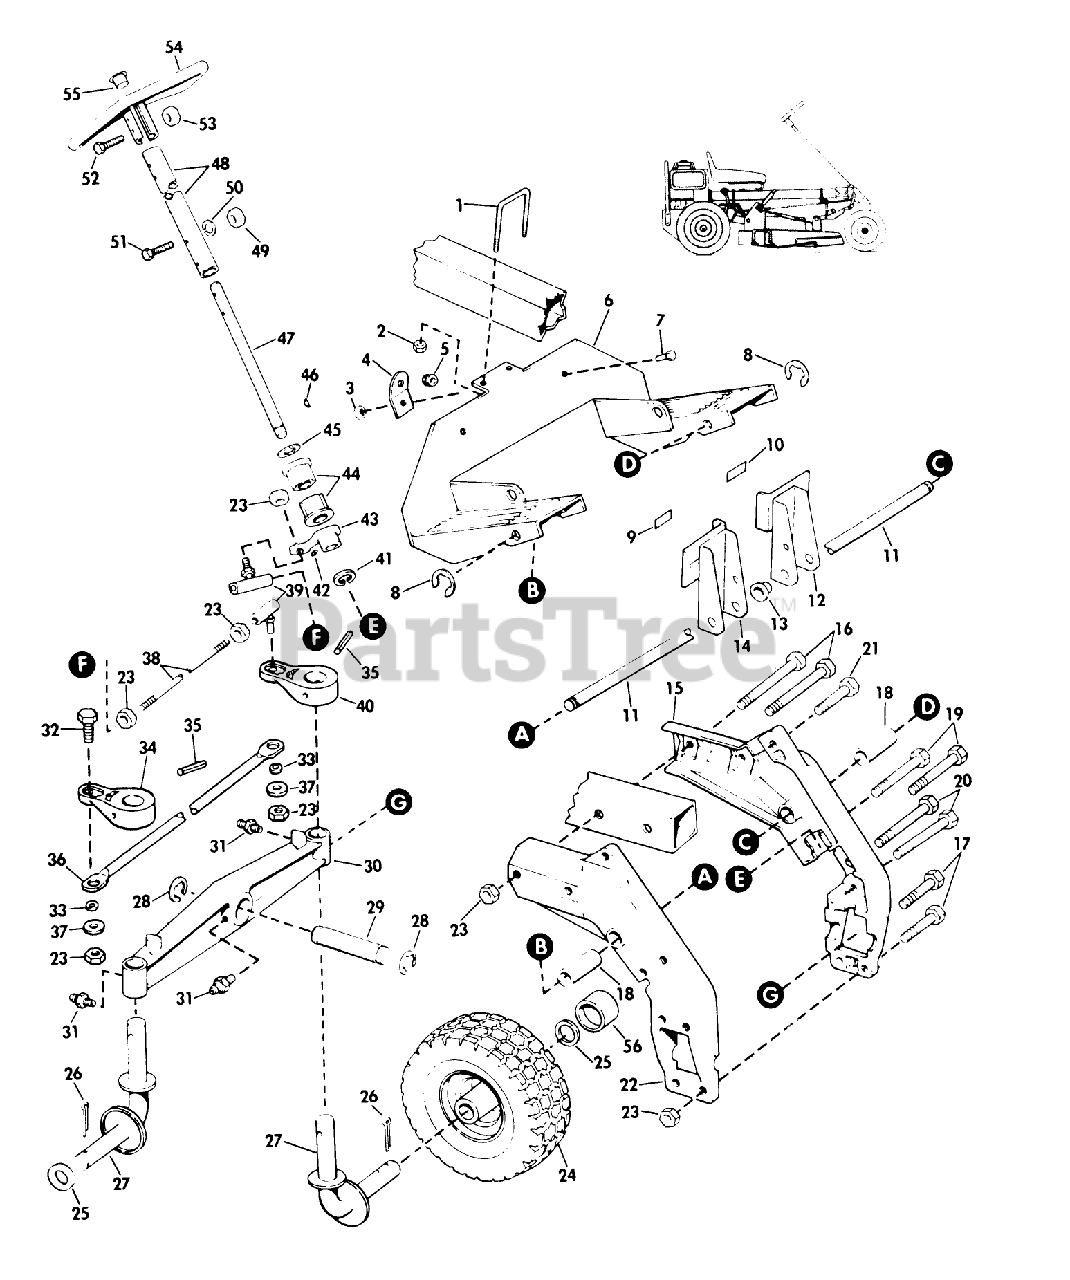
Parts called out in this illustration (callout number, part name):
5	Bushing
26	Cotter Pin-Front Wheel
31	Grease Fitting
32	Screw-King Pin
53	Nut-Steering Shaft
